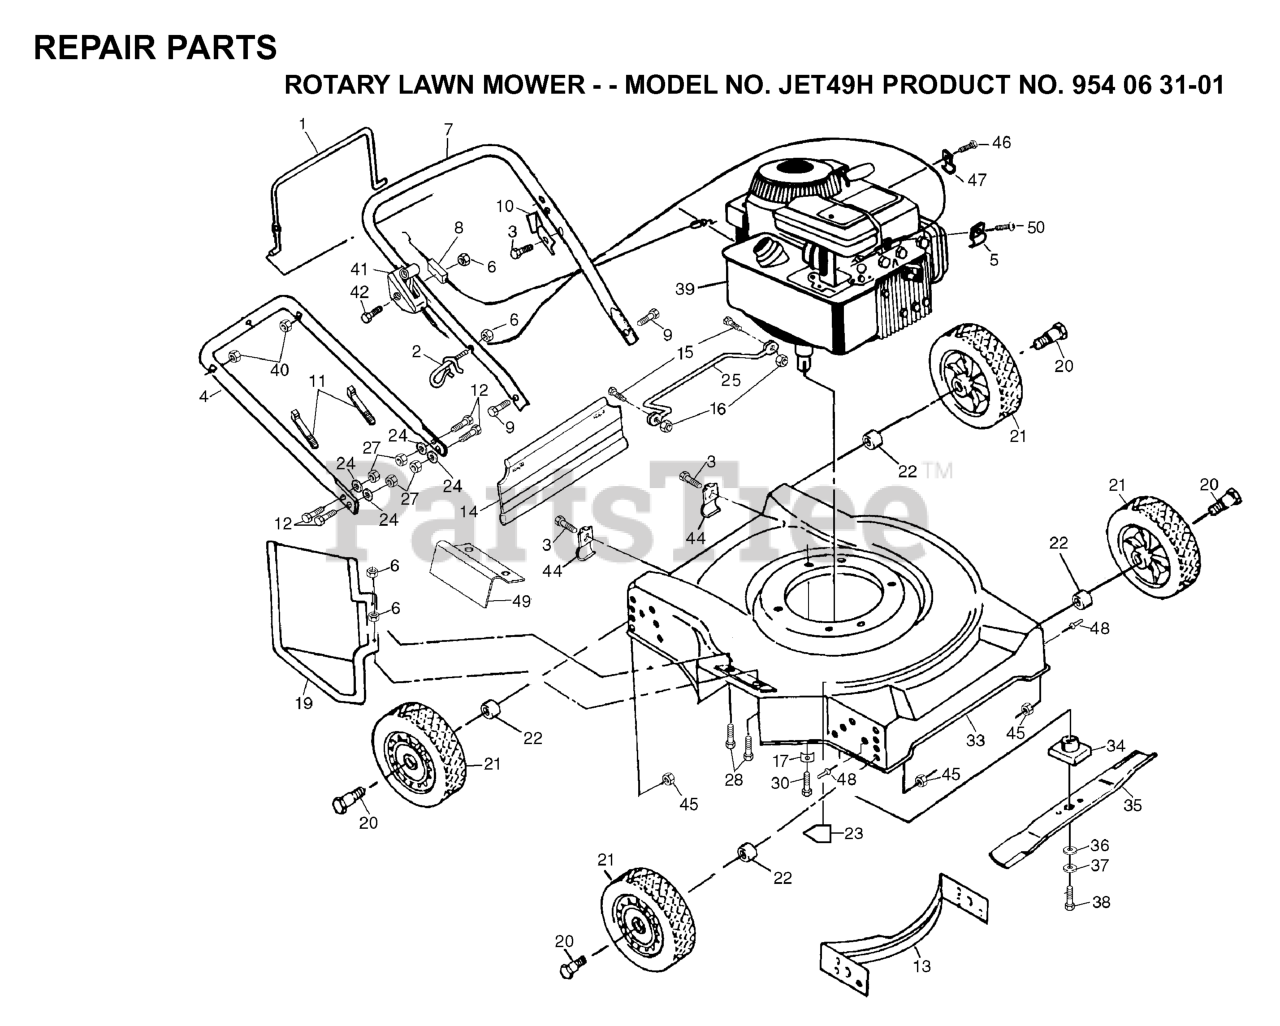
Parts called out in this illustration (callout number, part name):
1	CONTROL BAR
2	ROPE GUIDE
3	TAPPING SCREW
6	NUT
7	HANDLE.UPPER.ECONOMY.BLACK.
8	CABLE, CONT ENG
9	BOLT
10	BRACKET UPSTOP
11	TIE GUIDE
13	FRONT BAFFLE
14	REAR SKIRT
15	REPL BY 817 02 10-08
17	WASHER.ENGINE.BZP
21	WHEEL
22	SPACER.WHEEL.390.X1.0X.380.RTA
23	DECAL MOWER CUT/FINGER
27	FLANGED LOCKNUT 3/8-16 ZINC
28	BOLT.HEX.1/4.X.3/4.DICHROMATE
30	BOLT 3/8-16X1-1/8
34	BLADE ADAPTOR
36	WASHER,HARDEN
37	LOCKWASHER
38	SCREW, HEX HD 3/8-24 X 1-3/8
40	NUT
41	CONTROL.THROTTLE.B&S.WALK
42	SCREW.PAN.HEAD
44	BRACKET DEFL PM
45	LOCKNUT PM
46	SCREW.HEX.HEAD.WASHER.10-16
47	GUIDE CLIP PM
50	REPL BY 817 02 10-08
